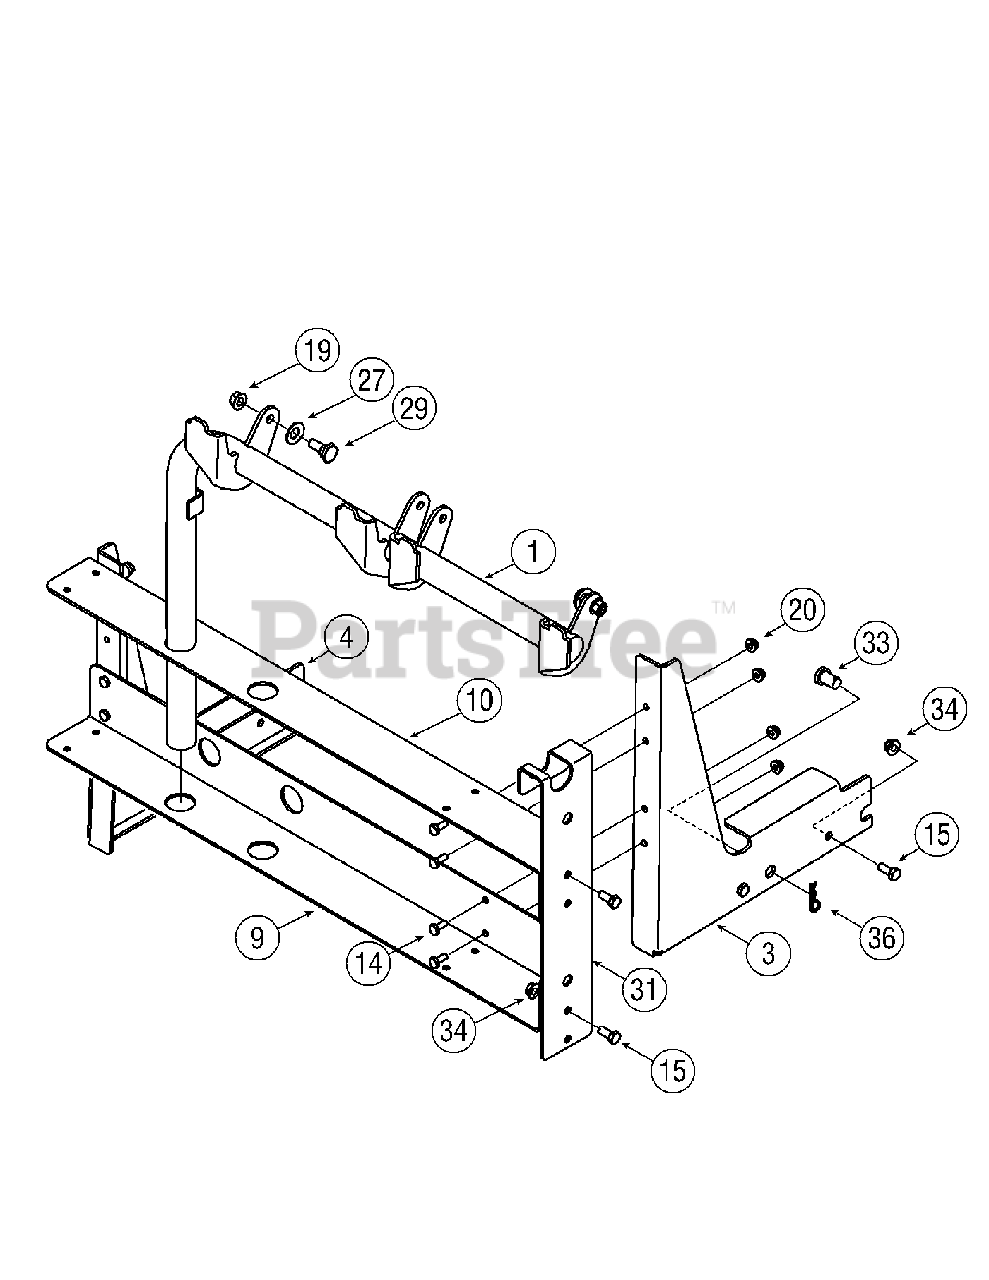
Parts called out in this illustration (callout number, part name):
14	Hex Bolt 1/4-20 x 0.75
15	Hex Bolt 5/16-18 x 1.00
19	Flange Lock Nut 3/8-16
20	Flange Lock Nut 1/4-20
27	Bell Washer
29	Shoulder Screw 3/8-16
33	Clevis Pin
34	Flange Lock Nut 5/16-18
36	Pin, Click, .092 x 1.64 Lg
